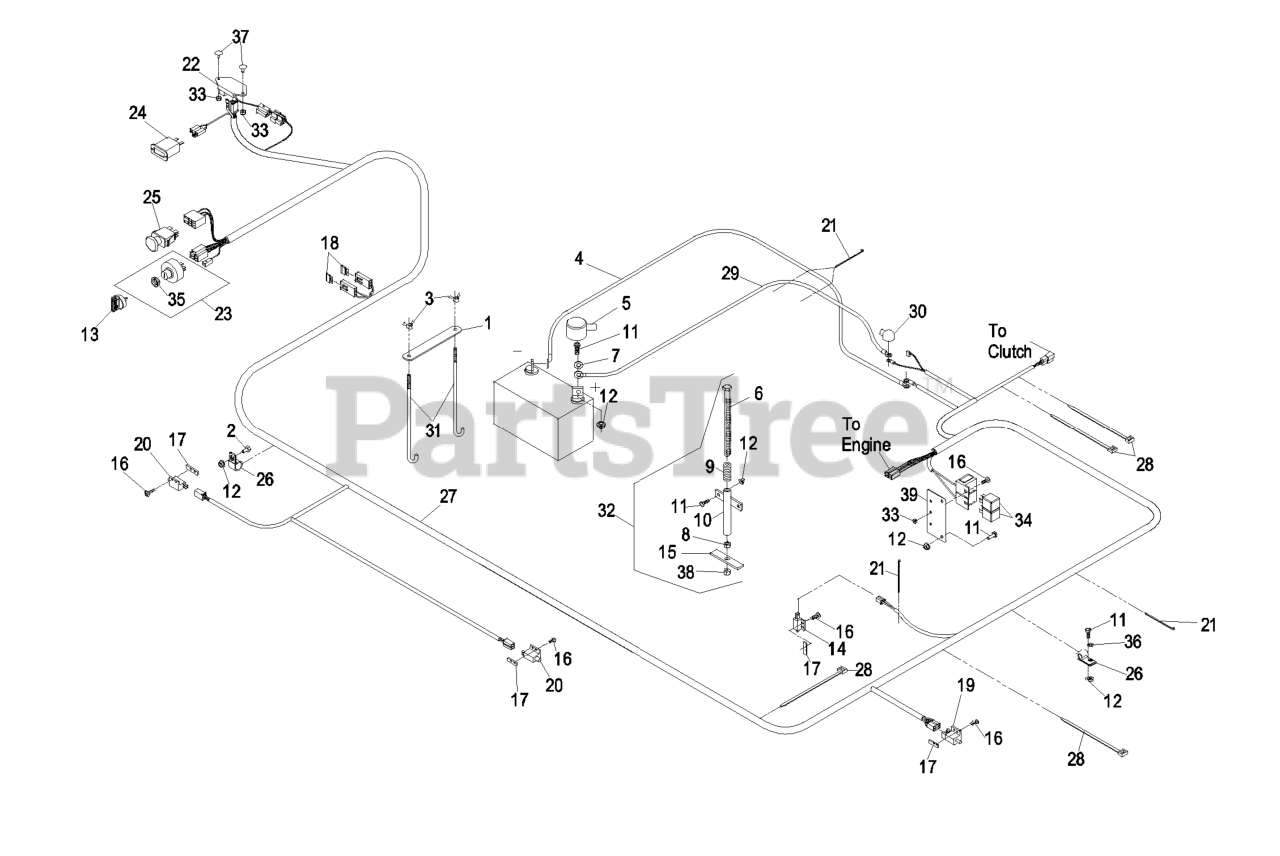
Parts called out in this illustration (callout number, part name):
1	STRAP-HOLDDOWN, BATTERY
2	SCREW-HH
3	WINGNUT
4	WIRE-GROUND
5	INSULATOR-BATTERY
6	SCREW-HH
7	WASHER-FLAT
8	NUT-HEX
9	SPRING-SWITCH, SEAT
10	MOUNT-SPRING, SEAT
11	SCREW-HH
13	KEY-IGNITION
14	SWITCH-CLOSED, NORMALLY
15	PLATE-SWITCH, SEAT
16	SCREW-PPH
17	PLATE-TAPPED
18	FUSE-BLADE TYPE, 20 AMP
20	SWITCH-OPEN, NORMALLY
21	TIE-CABLE
22	MODULE-DELAY, SEAT
23	ASM,SWITCH W/NUT
24	METER-HOUR
25	SWITCH-PTO
26	CLIP-LOOM
27	HARNESS, WIRE LAZER KC
28	TIE-PLASTIC
29	POSITIVE BATTERY CABLE AS
30	INSULATOR-SOLENOID
31	BOLT-HOLDDOWN
32	ASM,SEAT SWITCH ACTUATOR
33	NUT-LOCK, NI
35	NUT-SWITCH, IGNITION
36	WASHER-FLAT
37	BOLT-CARR
38	NUT-LOCK, NI
39	MOUNT-RELAY
